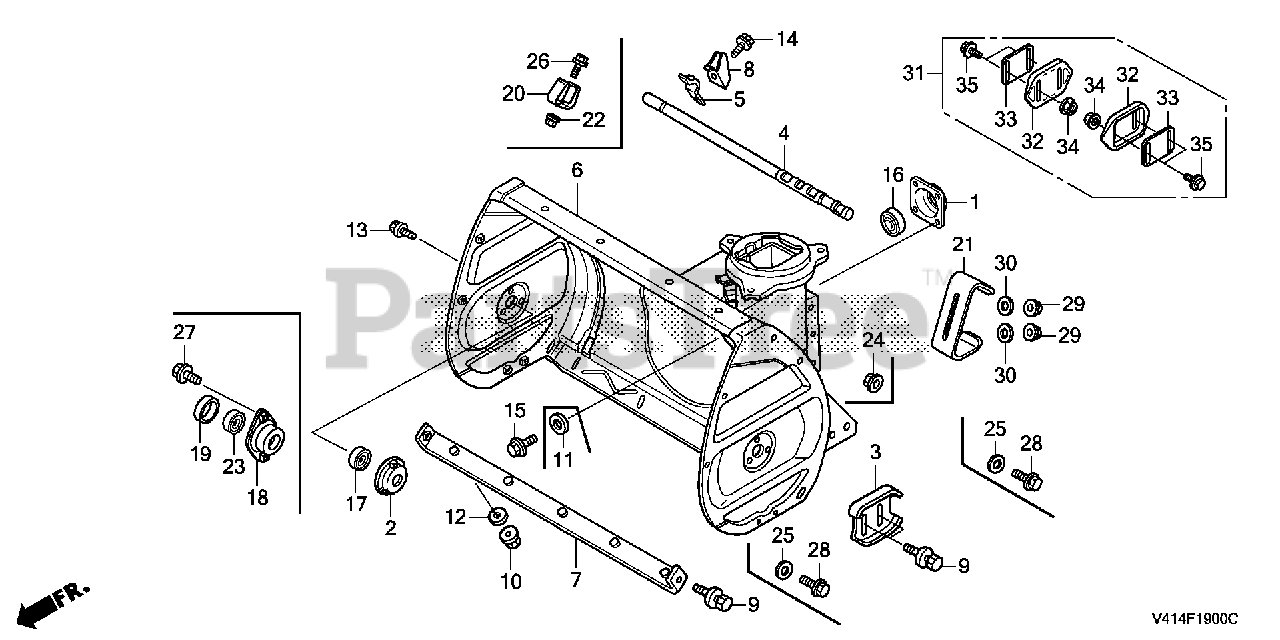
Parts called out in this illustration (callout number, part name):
1	HOLDER, BLOWER SHAFT BEARING
3	SKID, AUGER
4	BAR, SNOW DROP
6	HOUSING, AUGER *R280* (POWER RED)
7	BLADE, SCRAPER
10	NUT, FLANGE (8MM)
12	WASHER, PLAIN (8MM)
15	BOLT, FLANGE (8X12)
16	BEARING, RADIAL BALL (6205UU)
18	HOLDER, AUGER BEARING
19	SPACER, AUGER BEARING
20	BRACKET, SNOW DROP BAR
21	SKID, AUGER
22	NUT, NYLON RING (6MM)
23	BEARING, RADIAL BALL (6203-19.05)
24	NUT, FLANGE (8MM)
25	WASHER, PLAIN (8MM)
26	BOLT, FLANGE (6X12) Use from Engine SN 2086984.
27	BOLT, FLANGE (8X12)
28	BOLT, FLANGE (8X16)
29	NUT, FLANGE (8MM)
30	WASHER, PLAIN (8MM)
31	RESIN SKID SHOE(KIT)
32	SKID, AUGER
33	PLATE, AUGER SKID
34	NUT, FLANGE (8MM)
35	BOLT, FLANGE (8X22)
